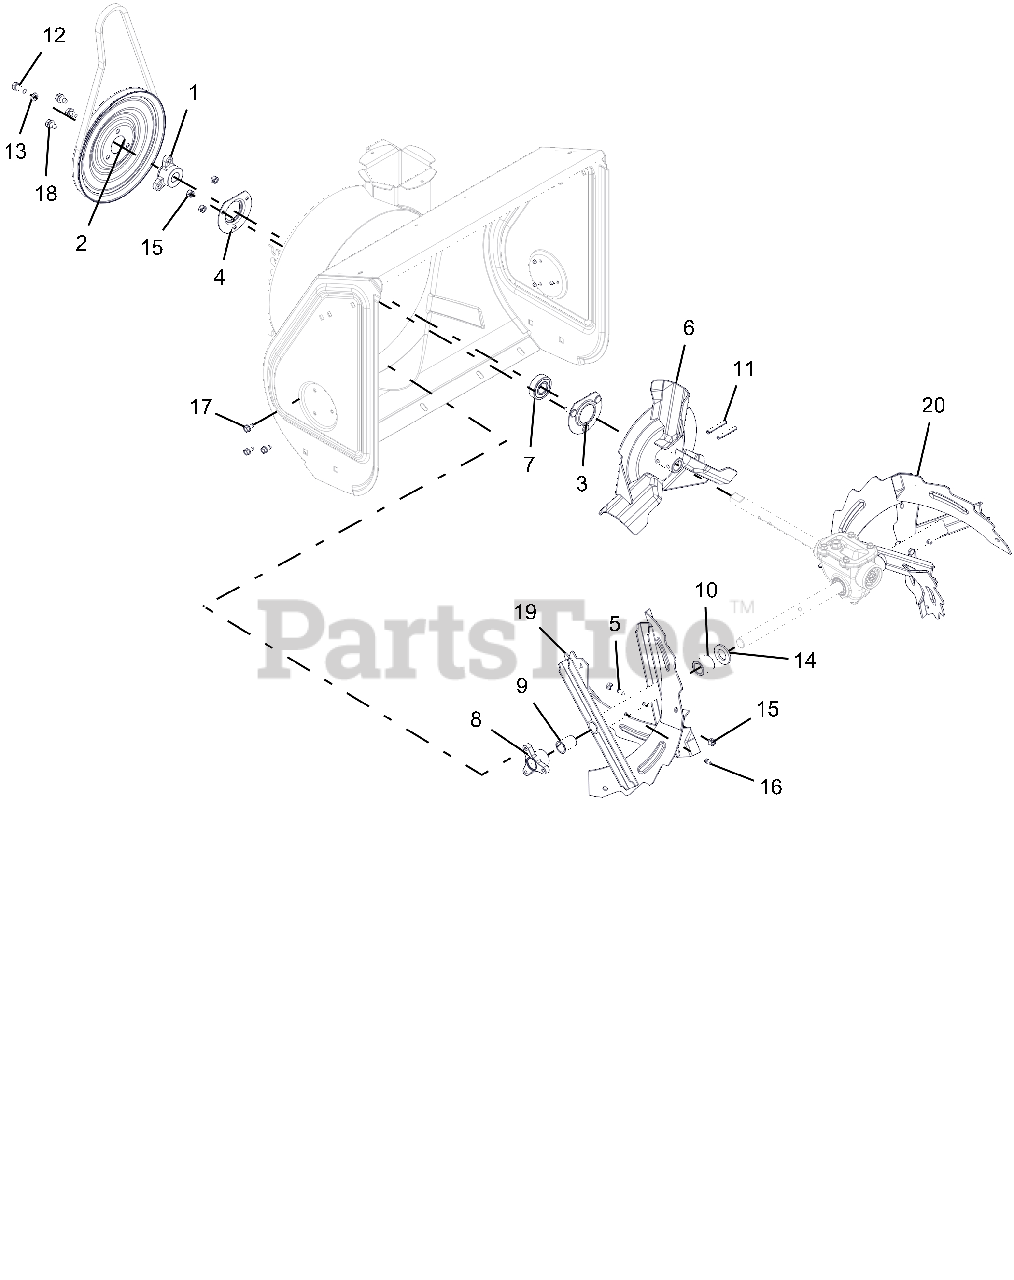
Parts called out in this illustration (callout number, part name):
1	PULLEY HUB, BOLT-ON D-BORE .75
2	PULLEY,SPIN FORM SINGLE GROOVE
3	BEARING FLANGE
4	BEARING FLANGE
5	SHEAR BOLT
6	IMPELLER, COMPACT 12" 3-BLADE
7	BRG-BALL .750X1.750X.50
8	BUSHING, RAKE SHAFT .75"
9	BSHG-FLG SPLIT NYLINER .75"ID
10	BSHG-SLV .75X1.12X1.062 NYL BK
11	PIN-ROLL .250X1.75
12	BLT-HEX .31-24X.75 YWZC GR5
13	WSHR-LK .312X.097 HVY YWZC
14	@WSHR-FL-STL.812X1.50X.135YWZC
15	@NUT-LK-CTR .25-20 YWZC
16	ZERK,FITTING .25X.125 DRIVE IN
17	SCR-TAP .25-20X.50 HWH TR YWZ
18	@SCR-TAP .31-18X.50 HWH TR YWZ
19	AUGER, 20" RH, BLK SERR W/ZERK
20	AUGER, LH 20", BLK SERR W/ZERK
